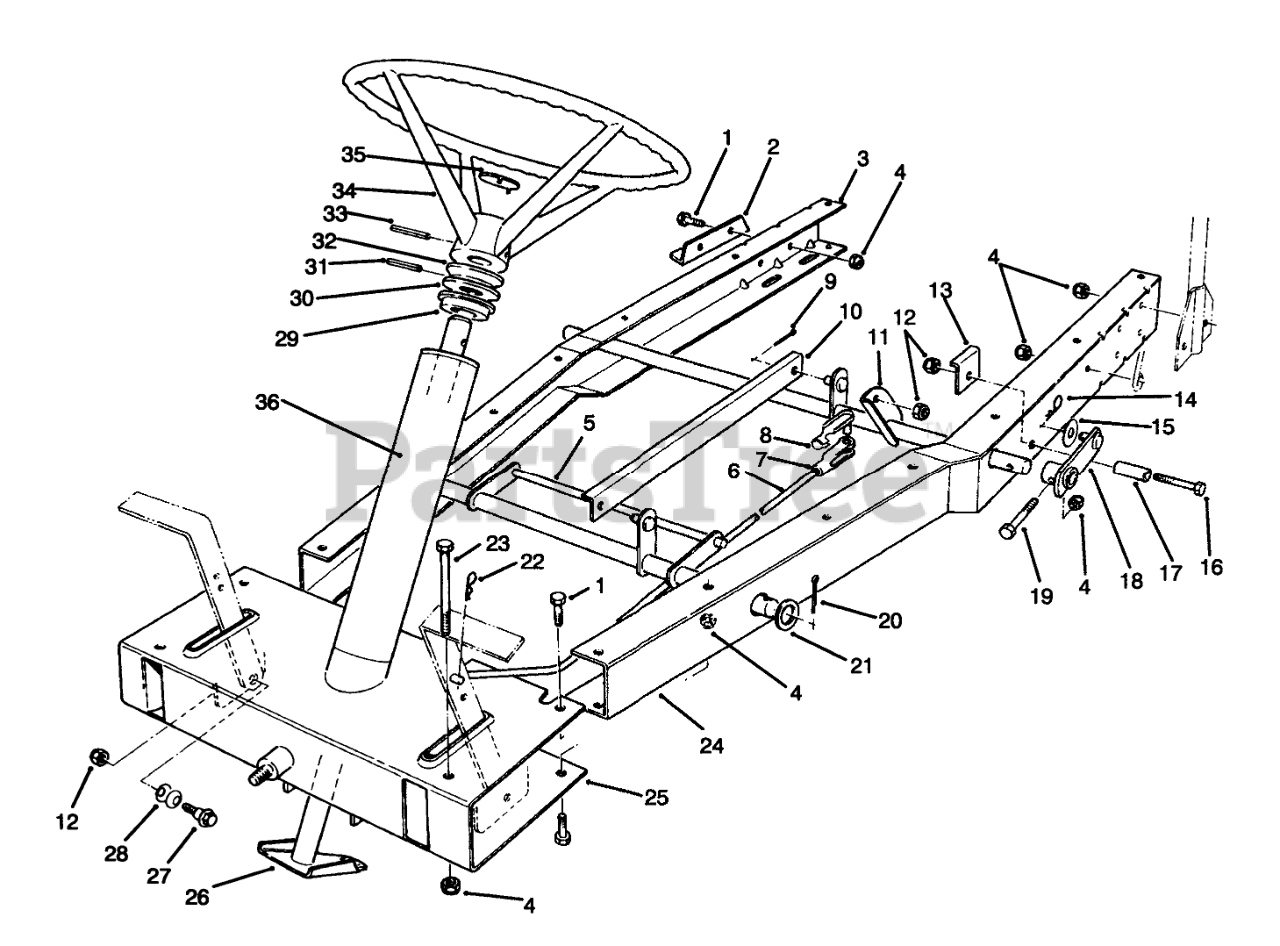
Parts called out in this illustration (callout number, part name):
1	SCREW-HH
2	MOUNT-AXLE BRG
3	FRAME-CHANNEL RH RED
4	NUT-LOCK, NI
5	FRT DECK LIFT WA BLACK
6	ROD-CLUTCH
7	CLEVIS-ADJ
8	CLEVIS PIN ASM
9	PIN-COTTER
10	BRACKET-HOC LINK
11	REAR SUP TUBE WA RED
12	NUT-LOCK, NI
13	DECK STOP BRACE (BLACK)
14	PIN-HAIR
15	WASHER
16	SCREW-HH
17	SPACER-STOP,DECK
18	HOC LEVER WA RED
19	AXLE MTG BOLT
20	PIN-COTTER
21	WASHER-FLAT
22	PIN-COTTER
23	SCREW-HH
24	FRAME-CHANNEL LH
25	FRONT FRAME WA RED
26	STEERING SHAFT WA BLK
27	BOLT-SHOULDER
28	WASHER-BELLEVILLE
29	BUSHING-STEERING
30	WASHER-STEERING
31	PIN-ROLL
32	SPACER-STEERING
33	PIN-ROLL
34	STEERING WHEEL ASM
35	INSERT - STRG WHL F/W
36	DECAL - STEERING COLUMN
